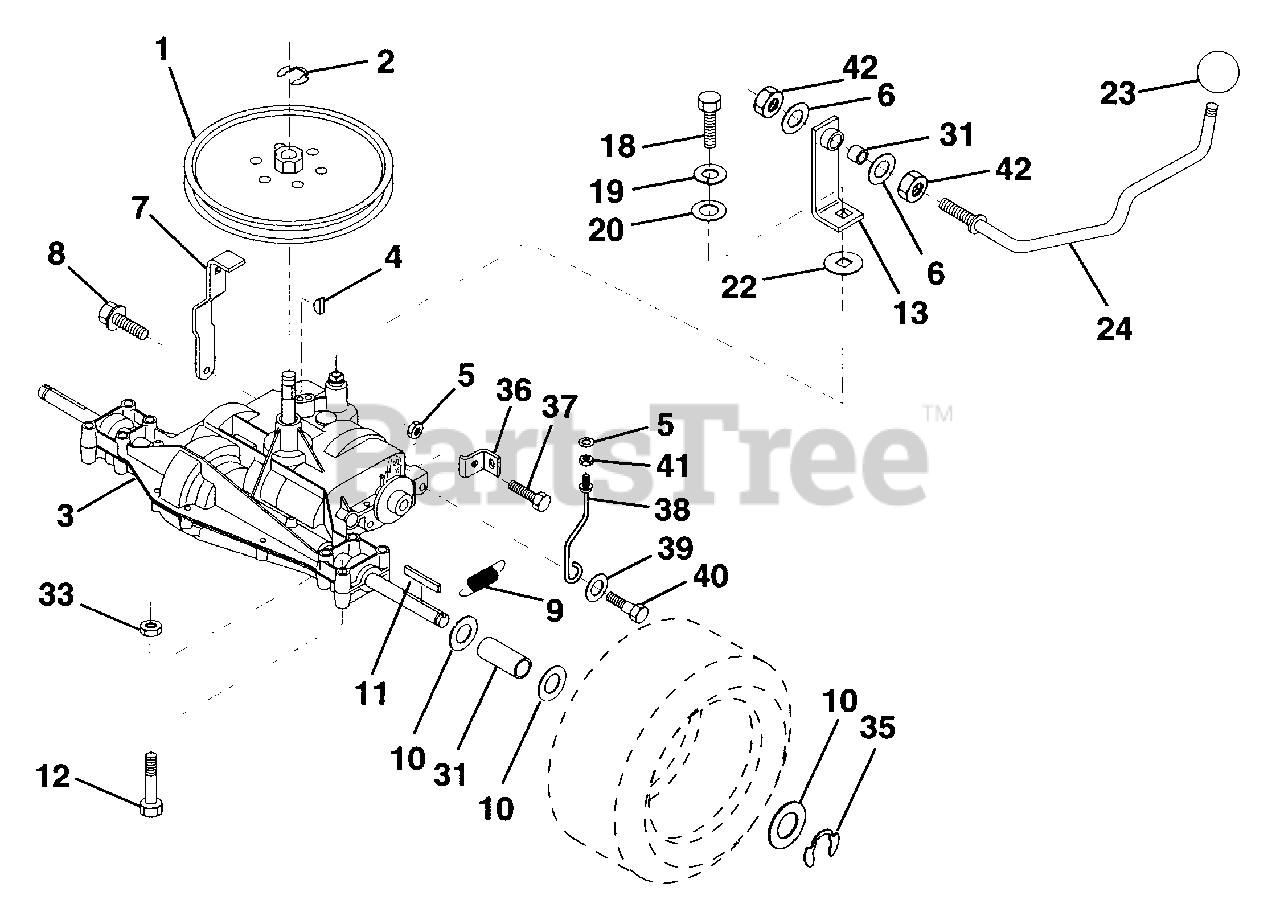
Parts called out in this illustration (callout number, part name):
2	Ring, Retainer
3	Transaxle, Peerless, 5 Speed
4	Key, Woodruff #9
5	Nut, Crownlock 5/16-18
6	Washer 15/32 x 1 x 12 Ga.
7	Strap, Torque
8	Screw, Hex Head, Thd. Roll. 5/16-18 x 3/4
9	Spring, Brake
10	Washer 25/32 x 1-1/4 x 16 Ga.
11	Key, Square
12	Bolt Fin Hex 3/8 - 16 x 2 3/4
13	Bracket Asm., Shft Cntr
18	Bolt, Hex Head, Fin. 1/4-28 UNF x 3/4 Grade 8
19	Washer, Lock 1/4
20	Washer 9/32 x 3/4 x 10 Gauge
22	Washer, Shift Plate
23	Knob, Shift Control
24	Rod, Shift Center
33	Nut, Crownlock 3/8 x 16 Unc
36	Bracket Brake
37	Bolt, Carriage 5/16-18 UNC x 3/4
38	Keeper Belt RH
39	Washer 1/32 x 1 x 12 Ga.
40	Bolt, Shoulder 5/26 - 18
41	Nut, Crowlock 5/16 - 18
42	Nut, Centerlock
